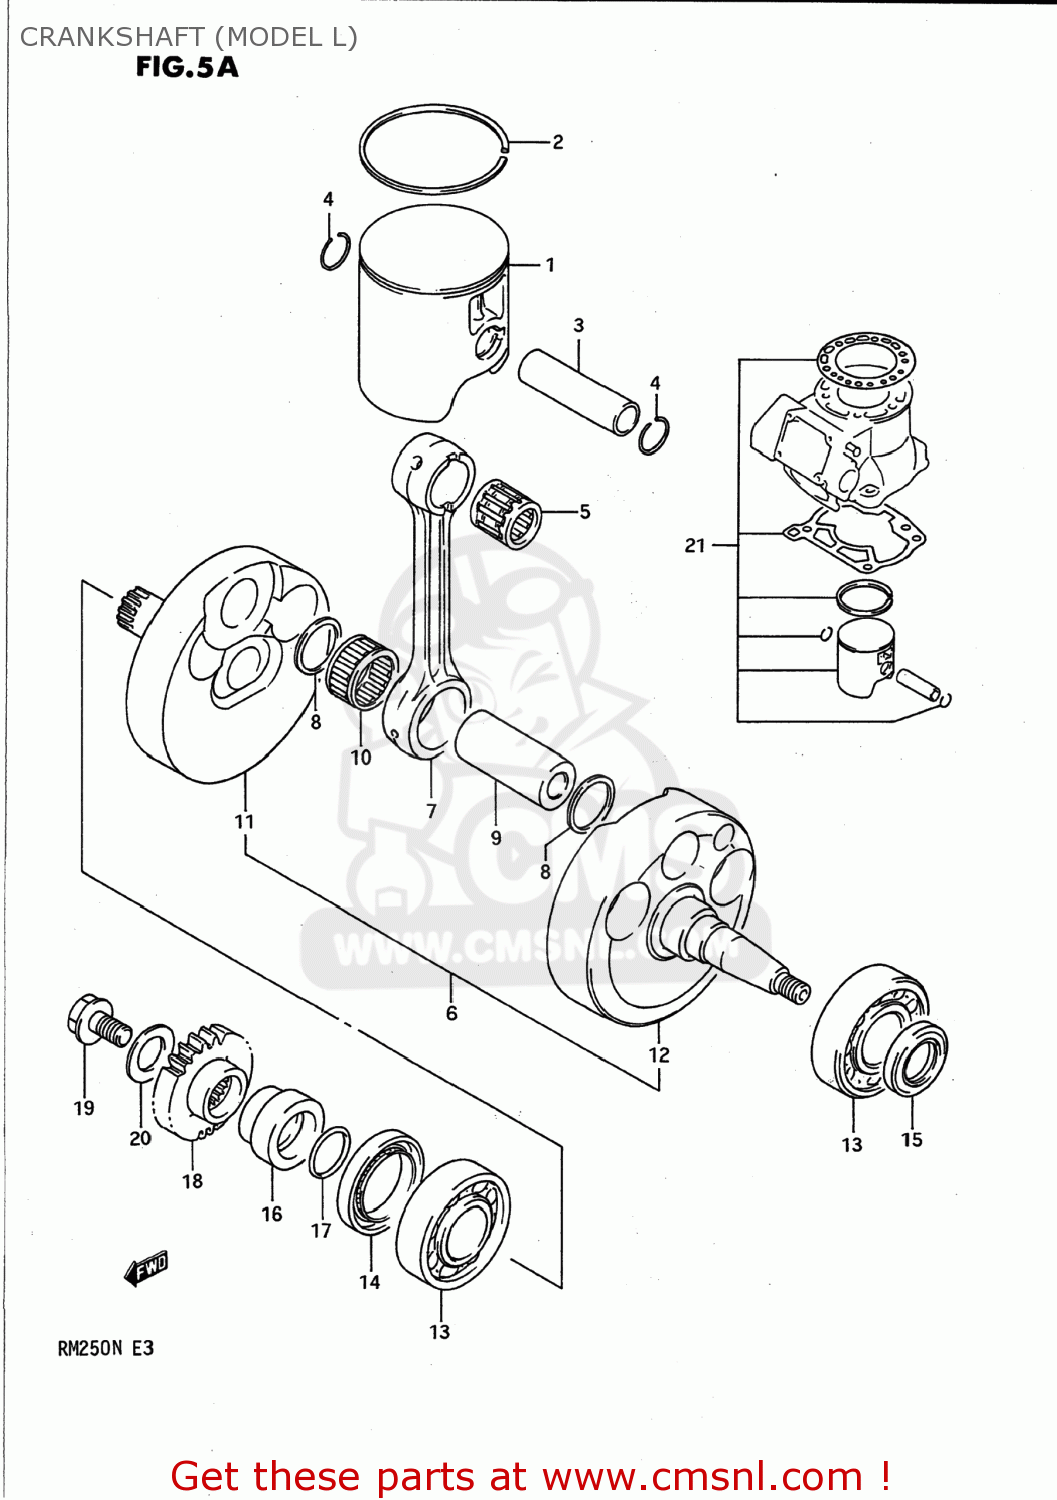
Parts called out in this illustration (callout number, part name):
1	PISTON
2	RING,PISTON
3	PIN,PISTON
4	CIRCLIP
5	BEARING(18X23X22)
6	CRANKSHAFT ASSEMBLY
7	CONNECTION ROD
8	WASHER(24X29X1.5)
9	PIN,CRANK
10	BEARING
11	CRANKSHAFT,RIGHT
12	CRANKSHAFT,LEFT
13	BEARING(25X62X17)
14	OIL SEAL
15	OIL SEAL
16	SPACER,PRIMARY DRIVE GEAR
17	O RING(D:2.4,ID:21.8)
18	GEAR,PRIMARY DRIVE
19	BOLT,PRIMARY DRIVE GEAR
20	WASHER
21	TOP END KIT,ENGINE
